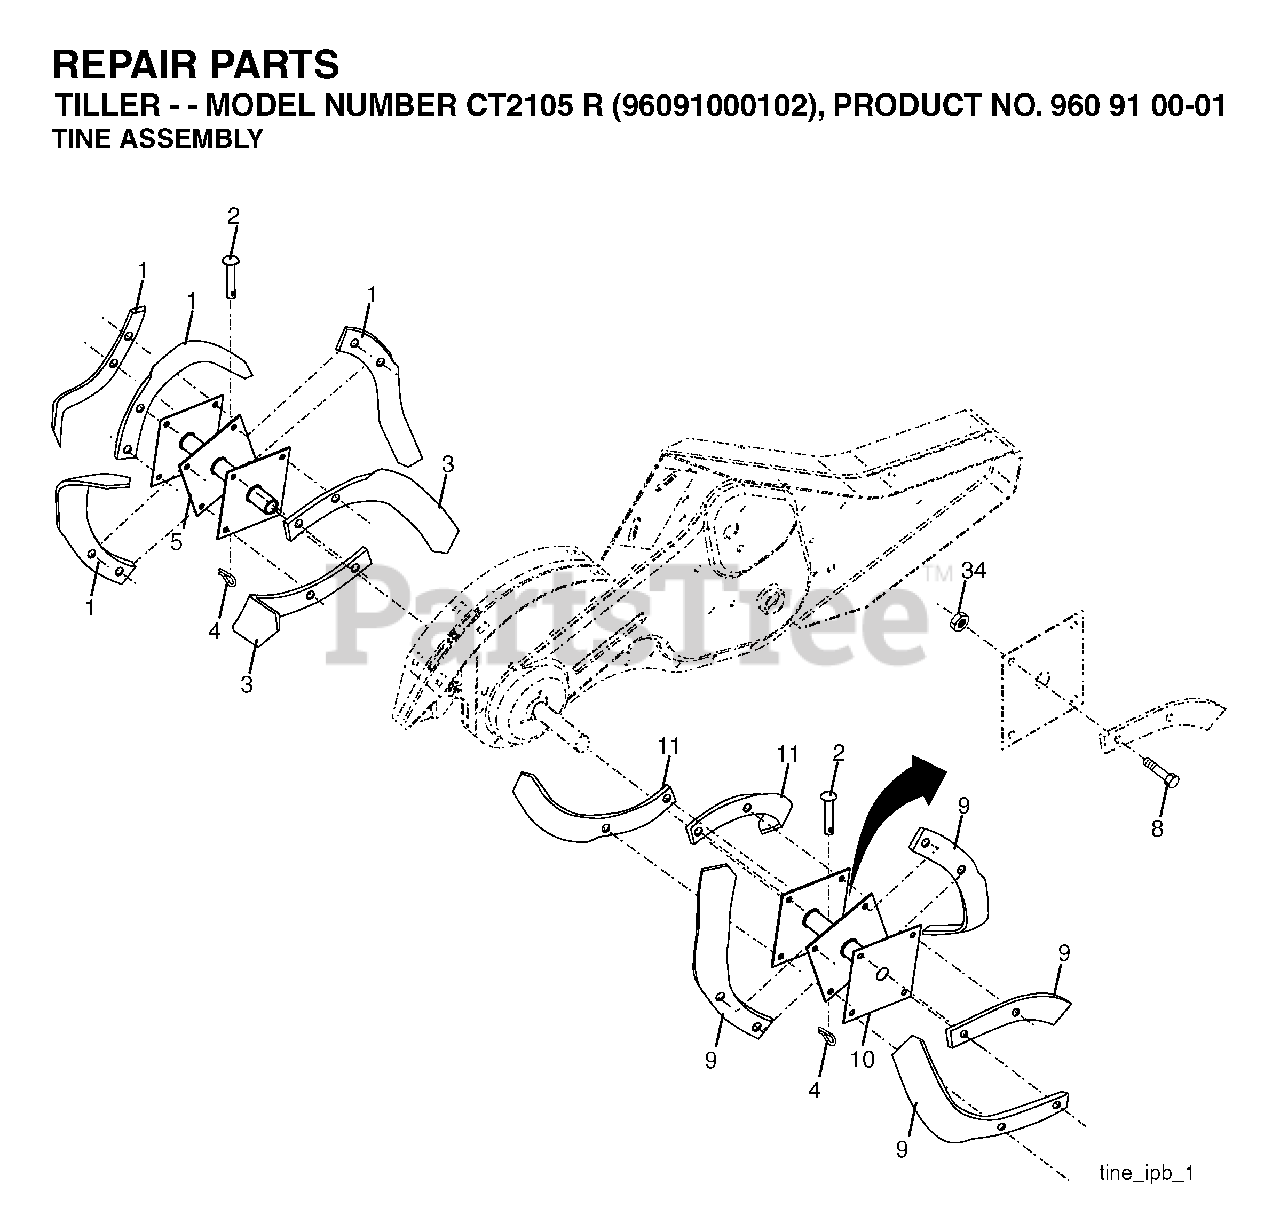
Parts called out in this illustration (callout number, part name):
1	TINE TI
2	CLEVIS PIN
3	TINE.LH.12"
4	SPRING RETAINER
5	HUB & PLATE ASM LH
8	BOLT.HEX.001X20.37-24X1.ZINC
9	TINE TI
10	HUB & PLATE ASM RH
11	TINE.RH.12"(72R)
34	NUT CROWNLOCK 3/8-24
